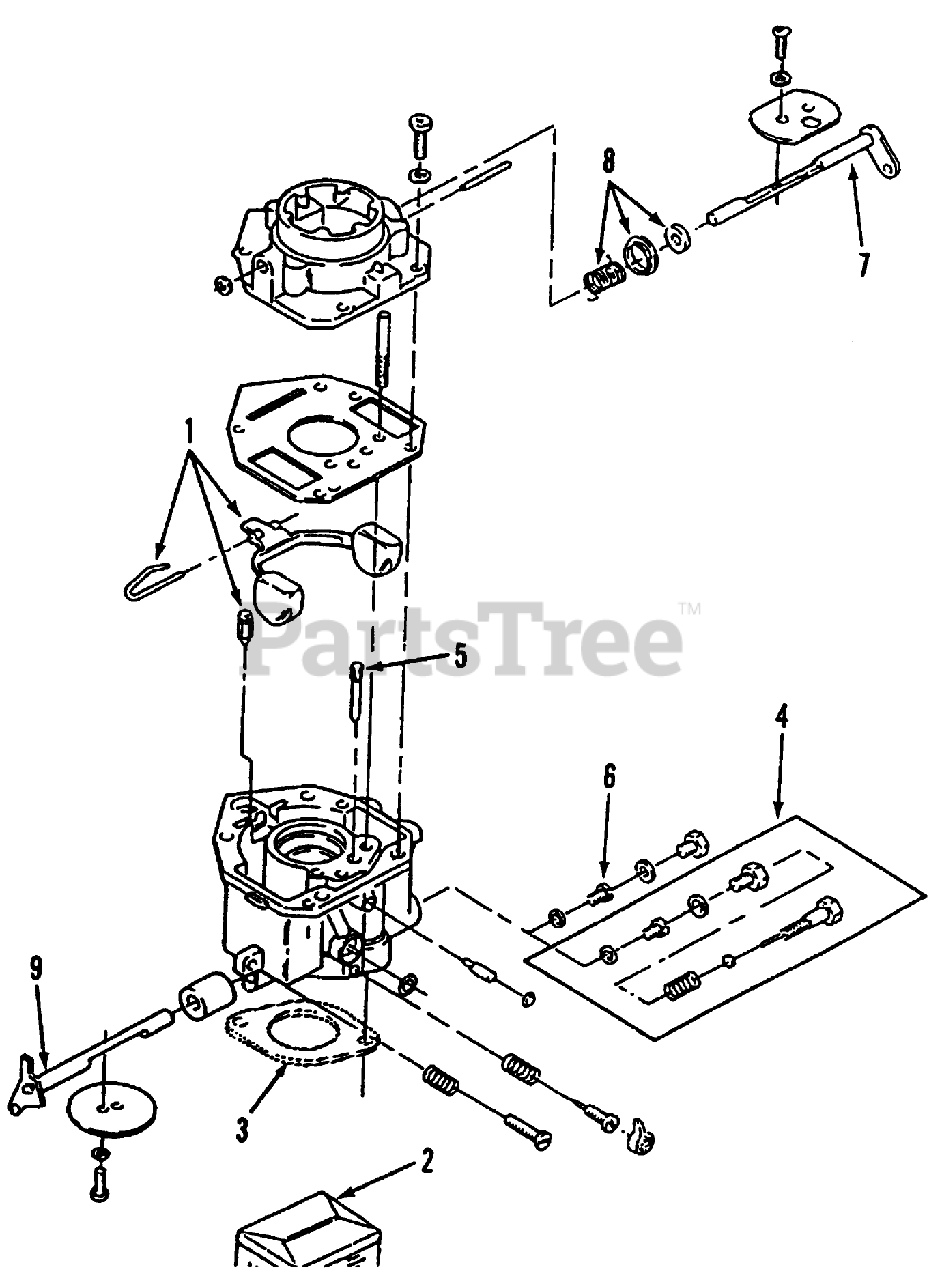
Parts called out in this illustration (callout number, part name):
2	REPAIR KIT
4	FIXED-JET
5	Jet-Idle
